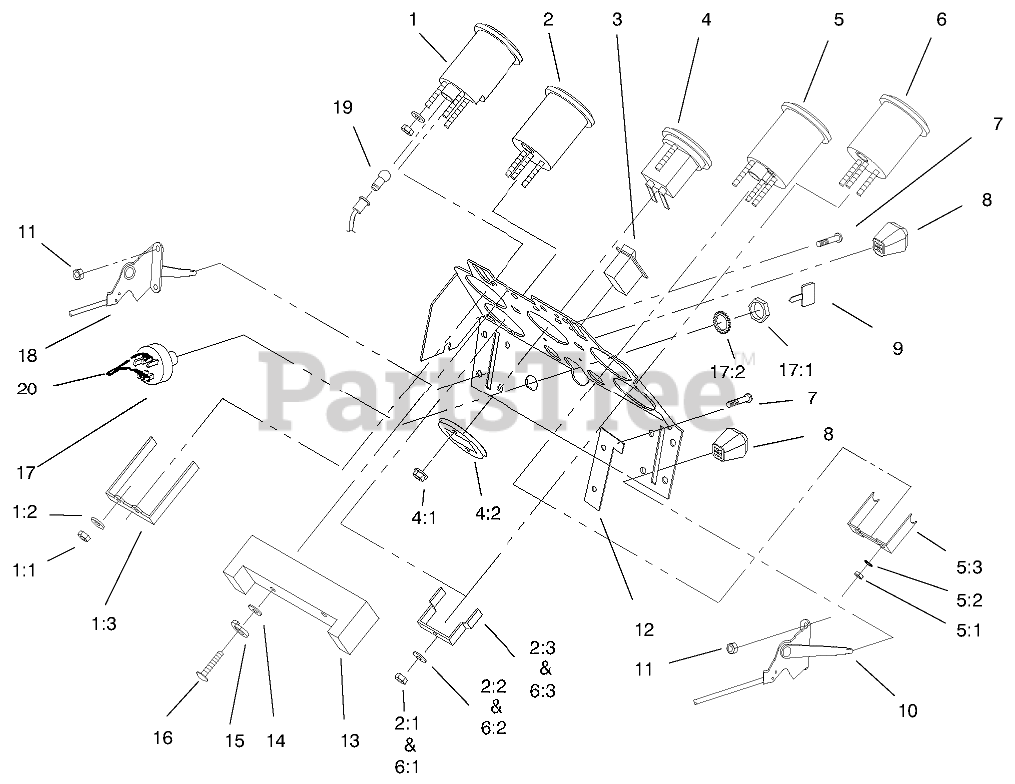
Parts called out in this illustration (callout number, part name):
1	TACHOMETER
1:1	NUT-HEX
1:2	WASHER-LOCK
1:3	BRACKET - GAUGE MOUNT
2	FUEL-GAUGE
2:1	NUT-HEX
2:2	WASHER-LOCK
2:3	CLAMP-MOUNTING
3	SWITCH-HEADLIGHT
4	Hourmeter
4:1	NUT-HEX, KEPS
4:2	Retainer
5	VACUUM-GAGE
5:1	NUT-HEX
5:2	WASHER-LOCK
5:3	Bracket-Mounting
6	Voltmeter
6:1	NUT-HEX
6:2	WASHER-LOCK
6:3	CLAMP-MOUNTING
7	SCRW-PHC
9	KEY-IGNITION
10	CONTROL-CHOKE
11	Nut
12	Stop-Choke
13	CIRCUIT-BRD 8 LIGHT
14	WASHER-FLAT
15	WASHER-LOCK
16	Screw
17	IGNITION SWITCH ASM
17:2	WASHER-LOCK
18	CONTROL-THROTTLE
19	LAMP-MINIATURE GE 53X
